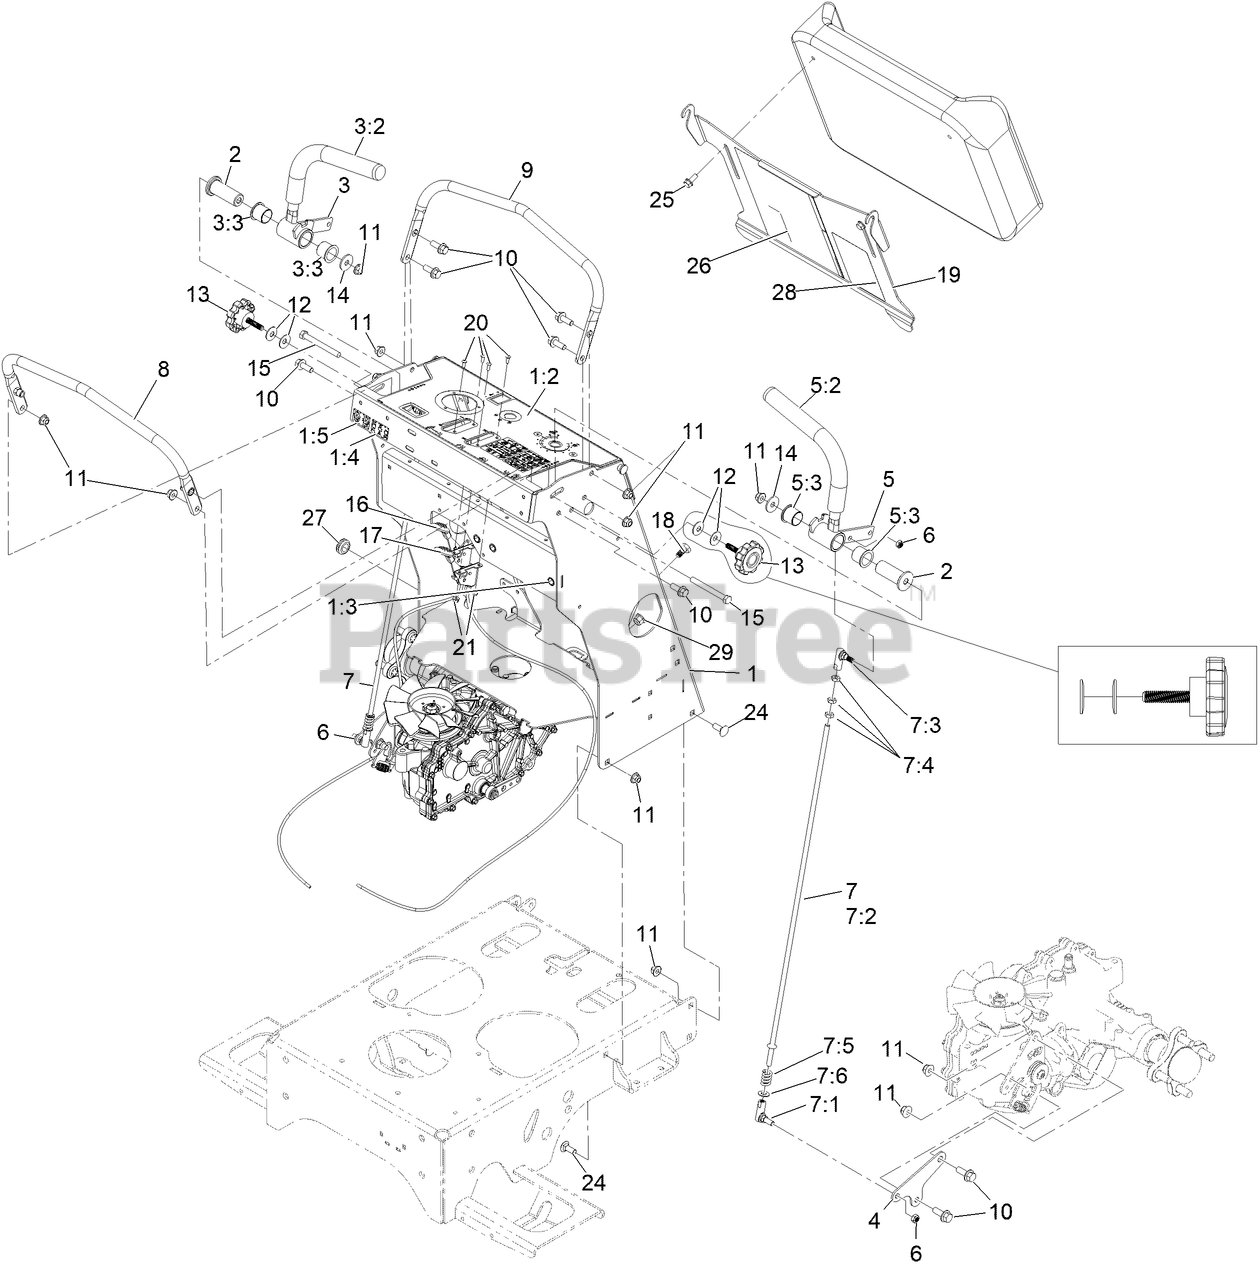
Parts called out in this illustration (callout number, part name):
1	TOWER-ASM W/DECAL
1:2	DECAL-CONTROL PANEL
1:3	NUT-CLINCH,HEX
1:4	DECAL-FUSE,MAIN
1:5	DECAL-FUSE,SOLID STATE
2	PIVOT-CONTROL, HANDLE
3	HANDLE-CONTROL, RH ASM
3:2	GRIP-CONTROL, MOTION
3:3	BUSHING-PIVOT
4	ARM-CONTROL, RTN
5	HANDLE-CONTROL, LH ASM
5:2	GRIP-CONTROL, MOTION
5:3	BUSHING-PIVOT
6	NUT-LOCK, NI
7	LINKAGE-MOTION CONTROL ASM
7:1	Balljoint-SS
7:2	ROD-CONTROL, MOTION
7:3	3/8-24 SS BALL JOINT\N367
7:4	Nut-Hex
7:5	SPRING-COMPRESSION
8	BAR-SPEED, ASM
9	BAR-REFERENCE
10	SCREW-HHF
11	Nut-Hex Flange
12	WASHER-SPRING
13	KNOB-FLUTED
14	WASHER-HARDENED
15	HHCS,3/8-16X3-1/2,ST/ST 18-8
16	CONTROL-THROTTLE
17	CONTROL,CHOKE
18	MAGNET-STUD, THREADED
19	PLATE-KNEE PAD
20	Screw-HSBH
21	Nut-Hex Flange
24	SCREW-CARR
25	SCREW-HHF
26	DECAL-SPRAY CHART
27	GROMMET
28	DECAL-SERVICE AID
29	NUT-LOCK, NI
